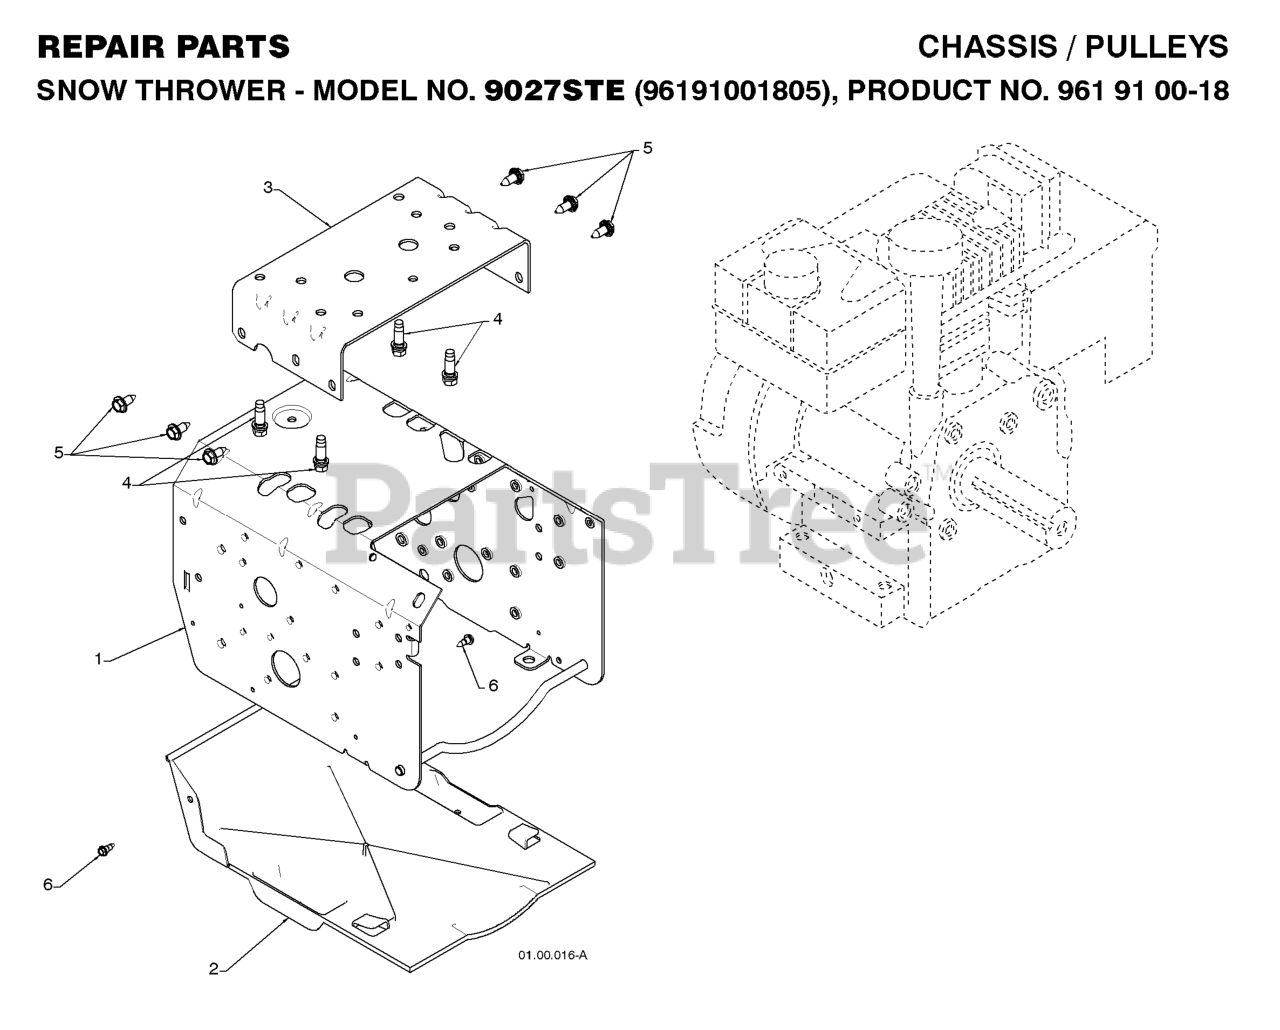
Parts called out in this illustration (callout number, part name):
1	FRAME.WELD.PNT.003BGP
2	PAN.BOTTOM.PLASTIC
3	PLATE.ENGINE.MOUNT.PNT
4	BOLT 3/8-16X1-1/8
5	SELF-TAPPING SCREW 5/16-18X3/4
6	SCREW, HEX HEAD, TAPPING
